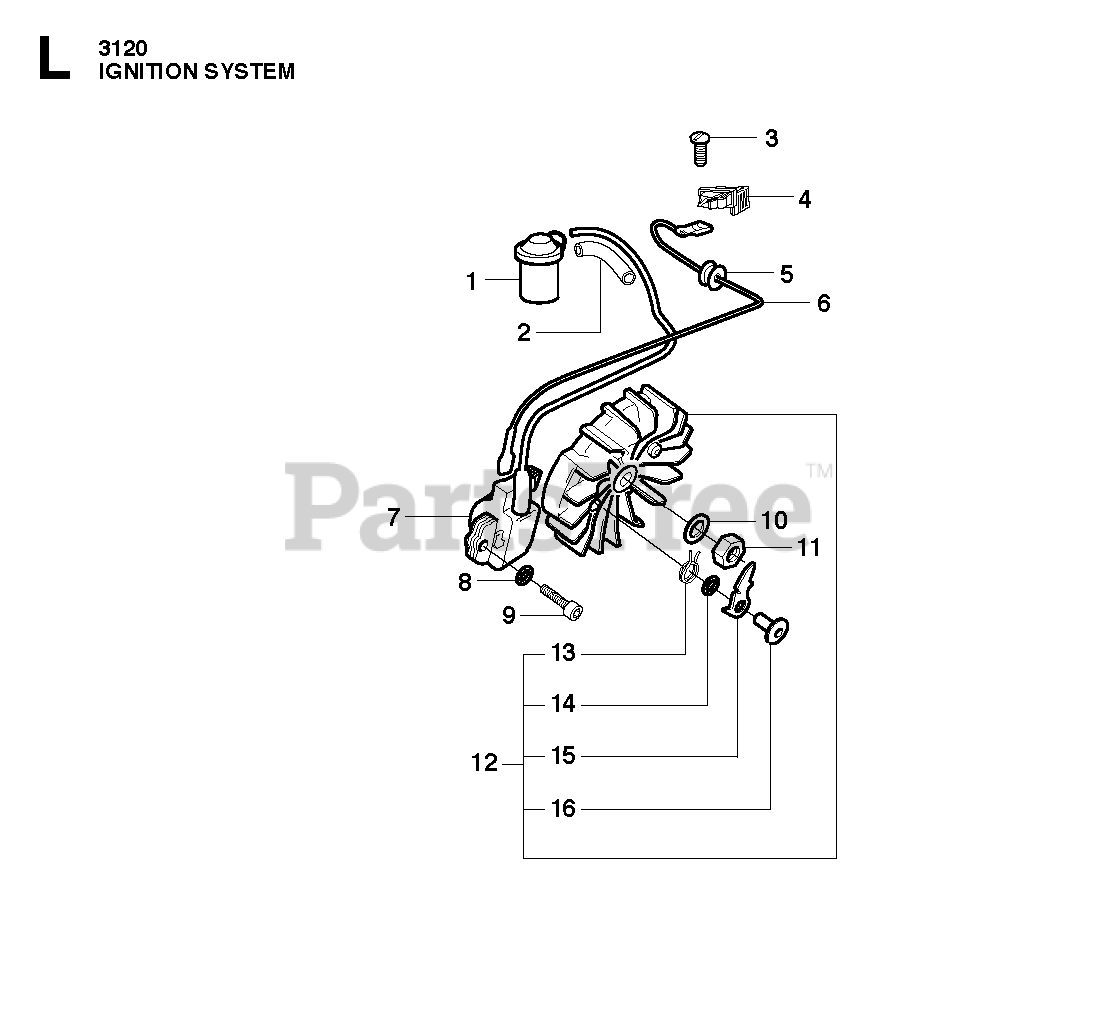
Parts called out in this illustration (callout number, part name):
1	SPARK PLUG CONN. KIT
4	SWITCH ON/OFF
7	ELECTRONIC BOX
7	IGNITION MODULE
8	WASHER 4.2X9
10	SPRING WASHER 10.5X18
12	FLYWHEEL
12	FLYWHEEL CPL
16	SCREW M5X14
